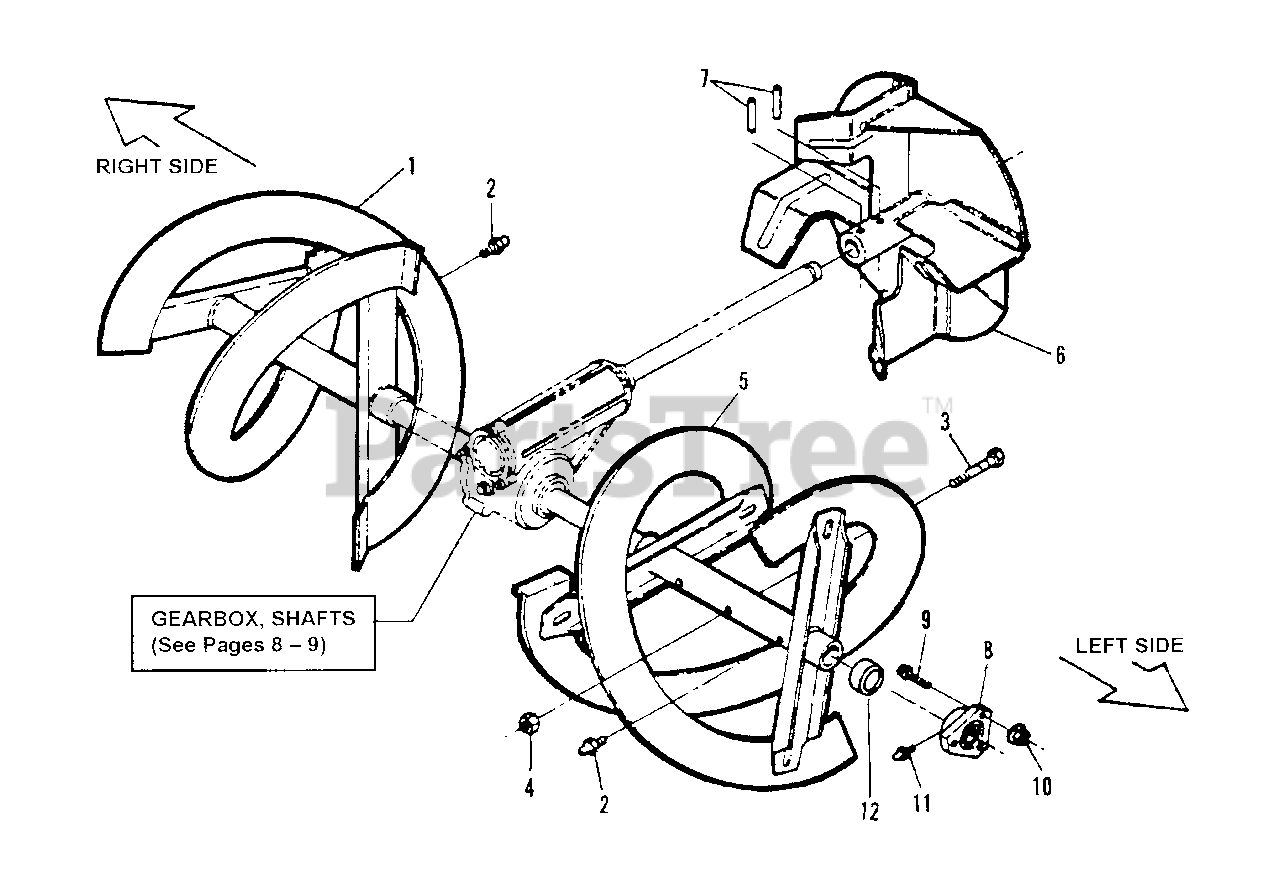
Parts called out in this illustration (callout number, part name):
1	AUGER, Right Side
2	LUBE FITTING, Straight (press-fit for .187 dia. Hole)
3	BOLT, 5/16-18 x 1-7/8" Shear
4	NUT, 5/16-18 Hex Nyloc
5	AUGER, Left Side
6	FAN, Impeller
7	PIN, 1/4 x 1-1/2" Roll
8	ASSEMBLY, Bearing
9	BOLT, 1/4-20 x 3/4" Hex Flange Lock, Grade 5
10	NUT, 1/4-20 Hex Flange Lock
11	FITTING, Lube (Press fit for .187 hole-no ball)
12	SPACER
